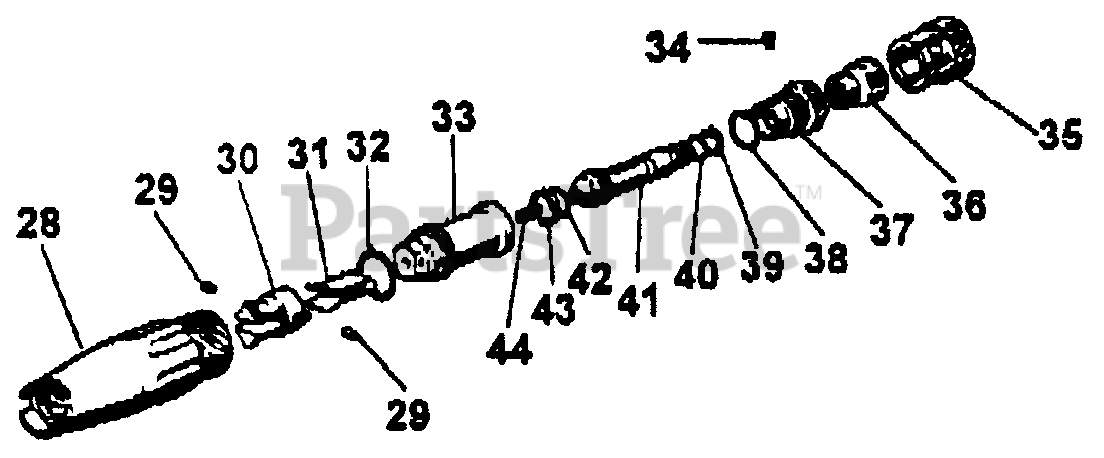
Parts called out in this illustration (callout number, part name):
28	KNOB, REGULATING
29	PIN
30	HOLDER, BLADE
32	O-RING 20 35×1 78
33	CYLINDER
34	PIN
35	KNOB, REGULATING
36	COUPLING
37	NUT, ADJUSTING
38	O-RING
39	RING, SEALING
40	O-RING 0.302×.070
41	TUBE
42	O-RING
43	SPACER
44	NOZZLE - RED
